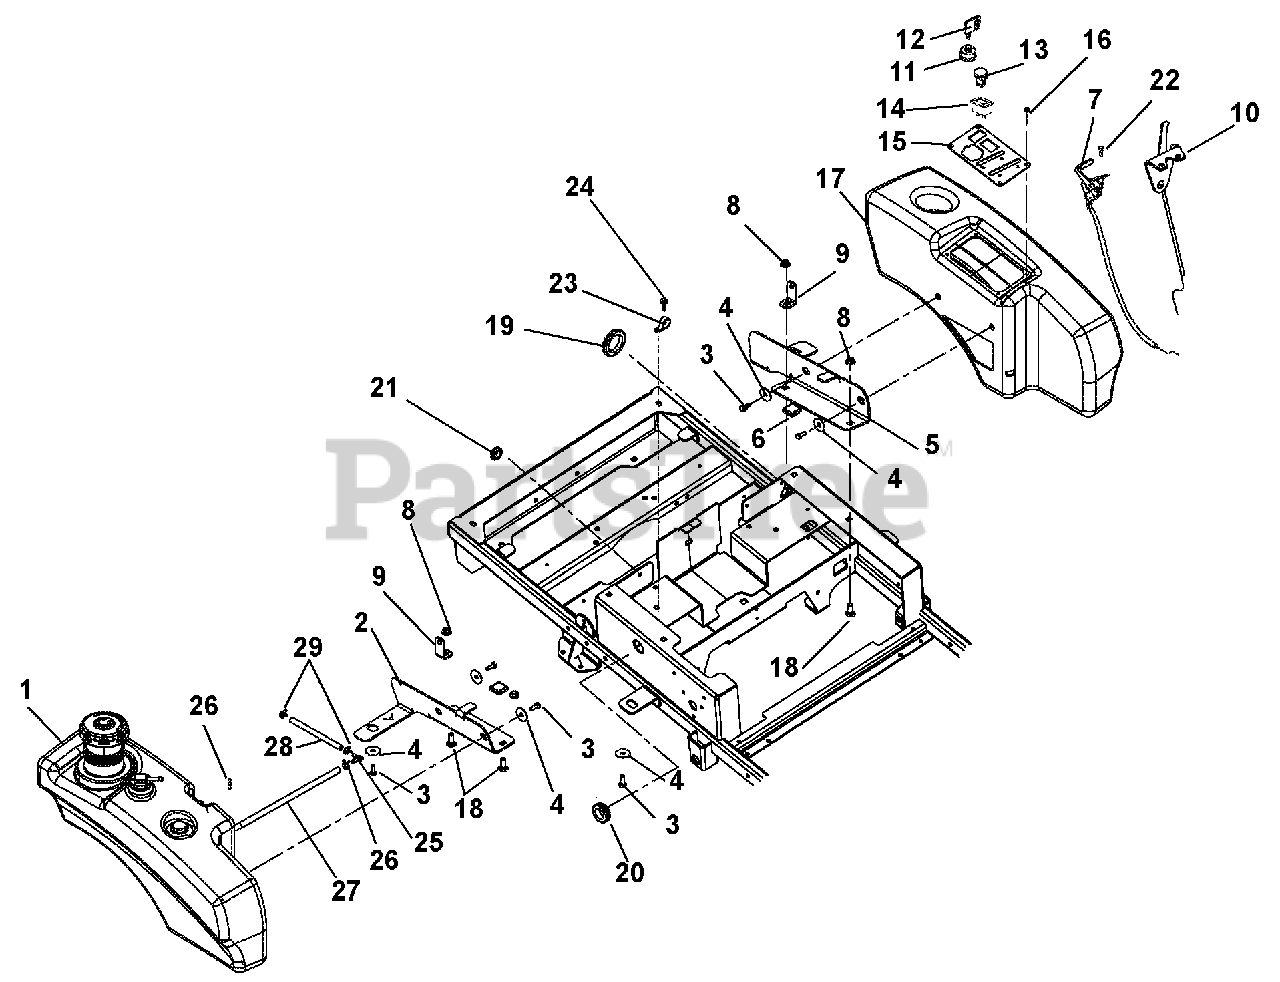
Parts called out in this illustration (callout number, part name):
1	TANK, XL NON-PERM ASSEMBLY
2	BRKT, RH REAR TANK MOUNT
3	BLT-SERHFWH .312-18X.50 YWZC
4	WSHR-FL-STL .347X1.254X.048YWZ
5	BRKT, LH REAR TANK MOUNT
6	GRIP, RUBBER (1.0X1.0X.187)BLK
7	CABLE, XL THROTTLE
8	@NUT-LK-NYL-FLG .38-16 YWZC
9	BRKT, HOOD PIVOT
10	CABLE, XL CHOKE
11	KEY SWITCH
12	KEY -W/CAP
13	SWITCH, CLUTCH
14	METER, HOUR W/MAINTENANCE
15	CONTROL PANEL
16	SCR-HEX .25X14-.75
17	FENDER, XL
18	@BLT-RDHDSQNK .38-16X1.00 G5YZ
19	GROMMET 1.70ID X 2.0OD
20	GROMMET 1.0ID X 1.38 OD
21	GROMMET,RUBBER 5/8 ID/1.13 OD
22	@SCR-TAP 10-24X.50 HWH TR YWZC
23	CLAMP, CUSHIONED STEEL .75
24	@SCR-TAP .38-16X.50 HWH TR YWZ
25	FITTING-3/16X1/4 90DEGREE VAC
26	CLAMP, FUEL LINE
27	HOSE, .25 LOW-PERM BULK GAS
28	HOSE, .188 LOW-PERM BULK GAS
29	CLAMP-HOSE, SPRING .188
30	CAP, END .315 X 1.00
